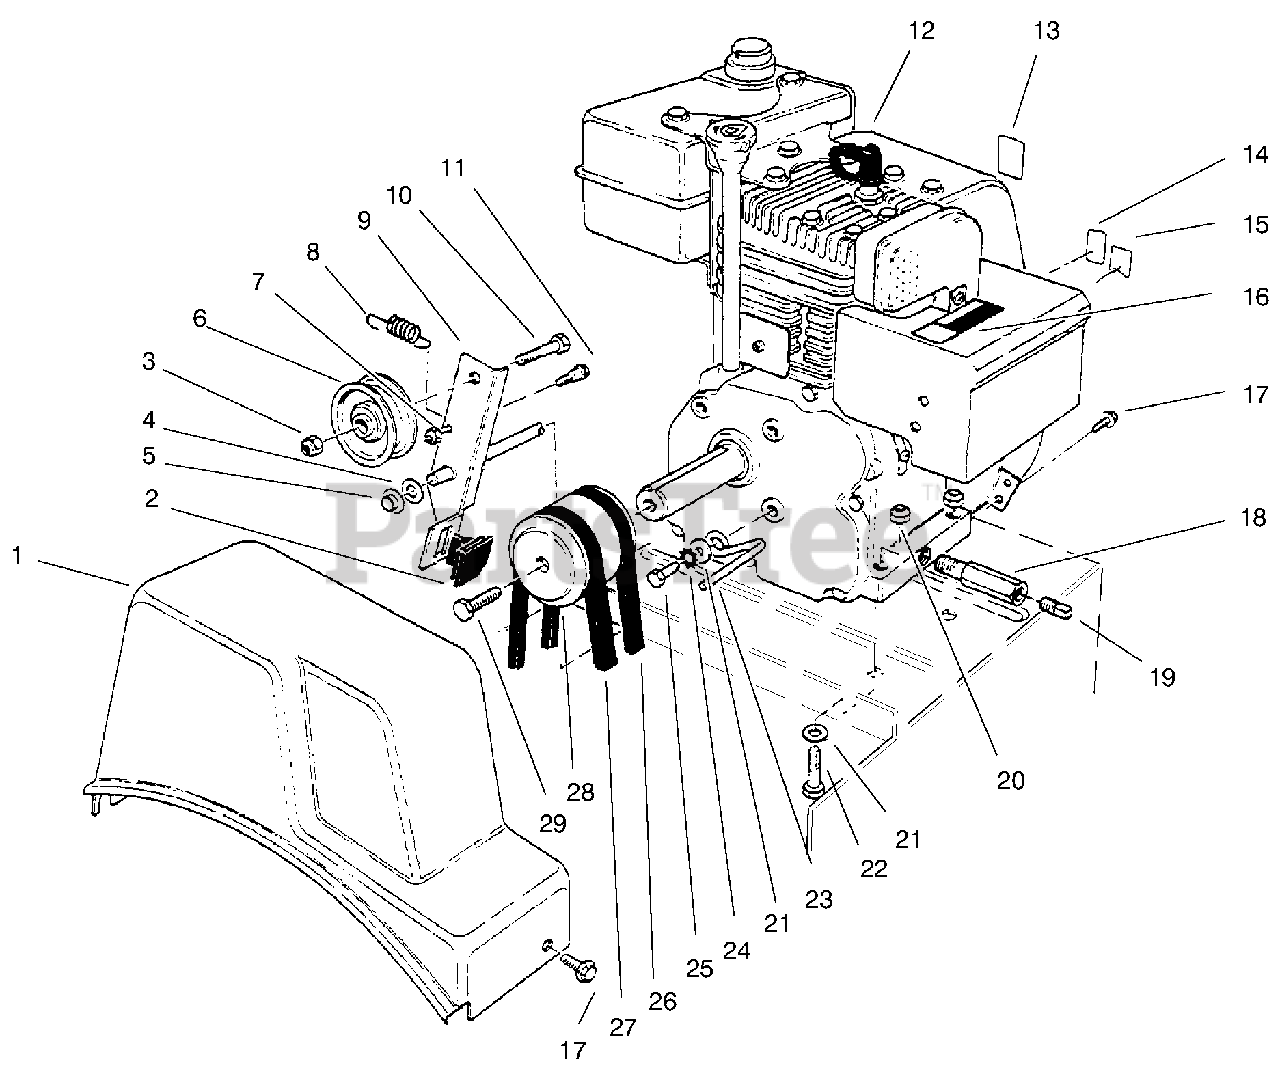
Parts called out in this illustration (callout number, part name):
1	Cover-Belt
2	Molded Brake Asm.
3	Nut-Lock
4	Washer-Flat
5	Nut-Push On
6	Idler Pulley
7	Nut-Lock
8	Spring-Auger Disengage
9	Auger Clutch (Incl. Ref. #2)
11	Bolt-Shoulder
12	Engine
13	Decal-Primer
14	Decal-Throttle
15	Decal-Choke
16	Decal-Hot Surface Warning
17	Screw-Self Tapping
18	Pipe-Drain
19	Plug-Pipe
20	Nut-Lock
21	Washer-Flat
23	Retainer-Belt
24	Washer-Lock Ext. Tooth
26	V-Belt-Traction
27	V-Belt-Auger
28	Engine Pulley
29	Screw-Special
